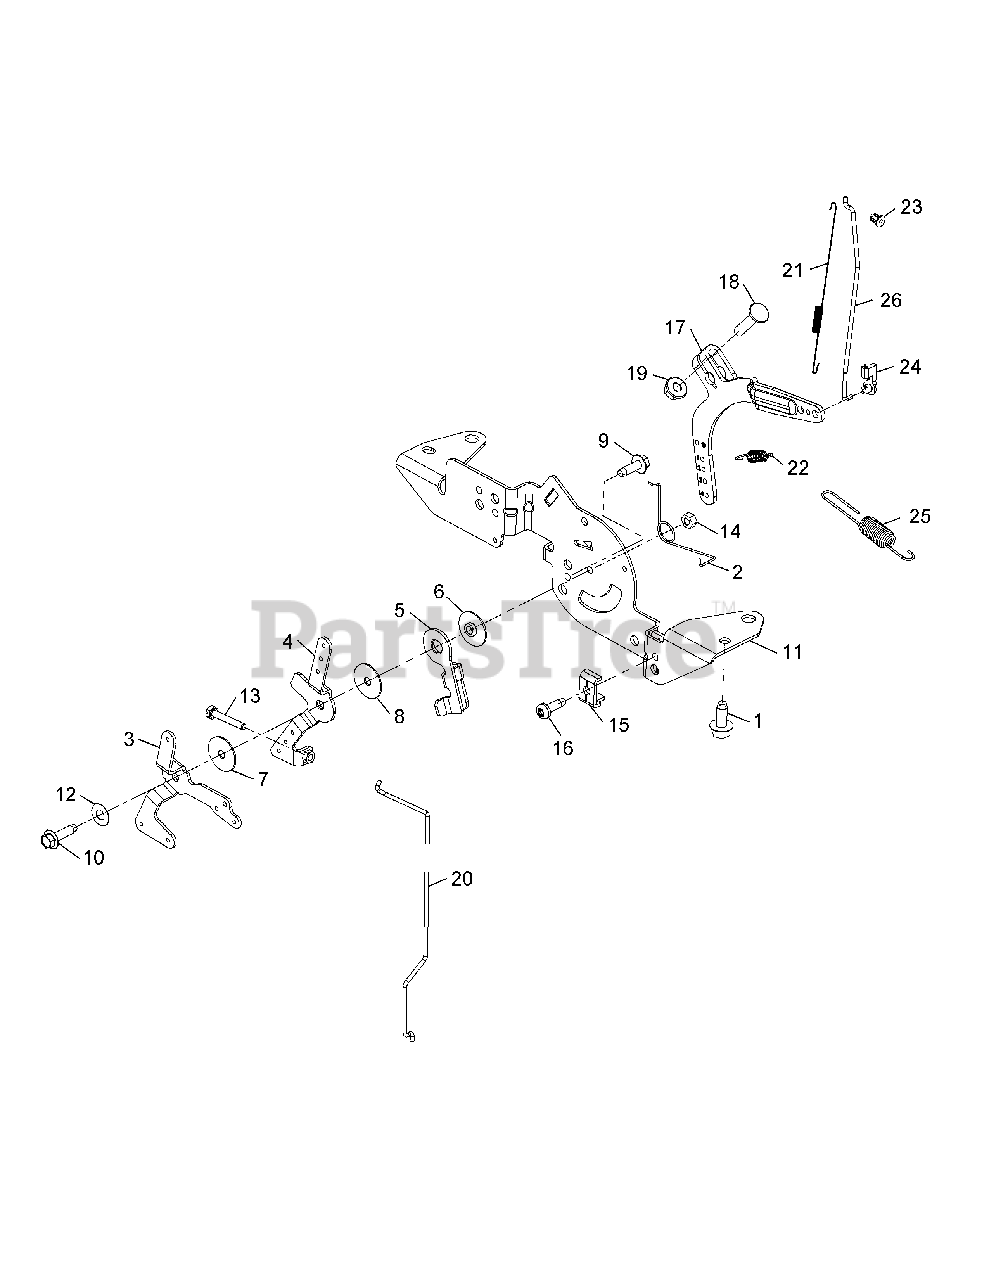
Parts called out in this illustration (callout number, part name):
1	Thread Forming Screw
2	Choke Return Spring
4	Throttle Control Lever
5	Throttle Actuator Lever
6	Control Assembly Spacer
7	Flat Washer, 5.5mm
8	Flat Washer, 5mm
9	Thread Forming Screw
10	Thread Forming Screw
11	Control Bracket
12	Spring Washer, 1/4
13	Screw, M4 x 0.7 x 25
14	Lock Nut, M5 x .8
15	Cable Clamp
16	Thread Forming Screw
17	Governor Lever
18	Bolt, M6 x 1.0 x 25
19	Flange Nut, M6 x 1.0
20	Choke Linkage
21	Linkage Spring
22	Governor Spring
23	Linkage Retaining Bushing
24	BUSHING-RETAINING
25	Governor Spring
26	Throttle Linkage
